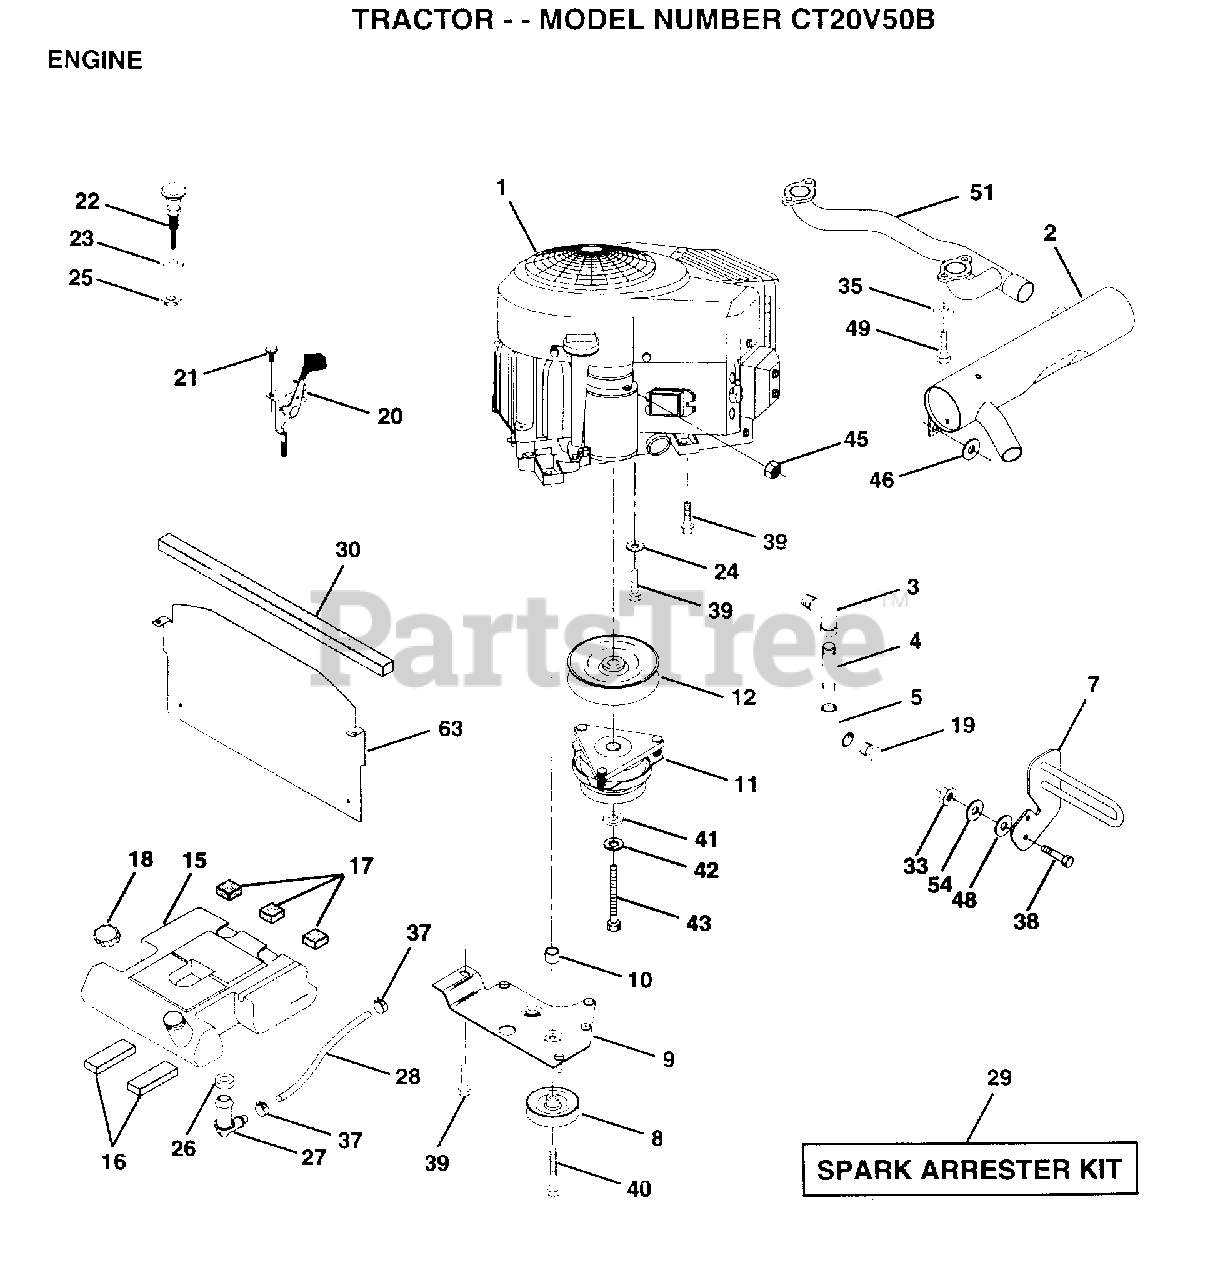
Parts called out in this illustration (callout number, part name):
3	STREET ELBOW LT
4	PIPE NIPPLE
5	ELBOW
7	GUARD.MUFFLER.ASM
10	BUSHING.
12	PULLEY.ENGINE.VGT
15	TANK FUEL REAR
16	PAD IDLER TI
17	PAD-SPACER LT
18	CAP ASM FUEL
19	PLUG T
21	SCREW LT
23	WASHER
24	LOCKWASHER
25	"NUT,KEPS 3/8-24IM"
26	BUSHING OUTLET T
27	STEM.TANK.FUEL
29	SPARK ARREST KIT
30	FOAM-STRIP LT
33	NUT
35	LOCKWASHER
37	HOSE CLAMP
38	"BOLT,HEX"
39	SCREW LT
40	SCREW.3/8-16X3.25
41	WASHER
42	LOCKWASHER
43	BOLT.7/16-20X4.25
45	NUT
46	WASHER HYT
48	WASHER T
49	BOLT.HD.SOCKET.
51	PIPE.EXHAUST.B&S
54	WASHER
63	SHIELD.HEAT.VGT.
